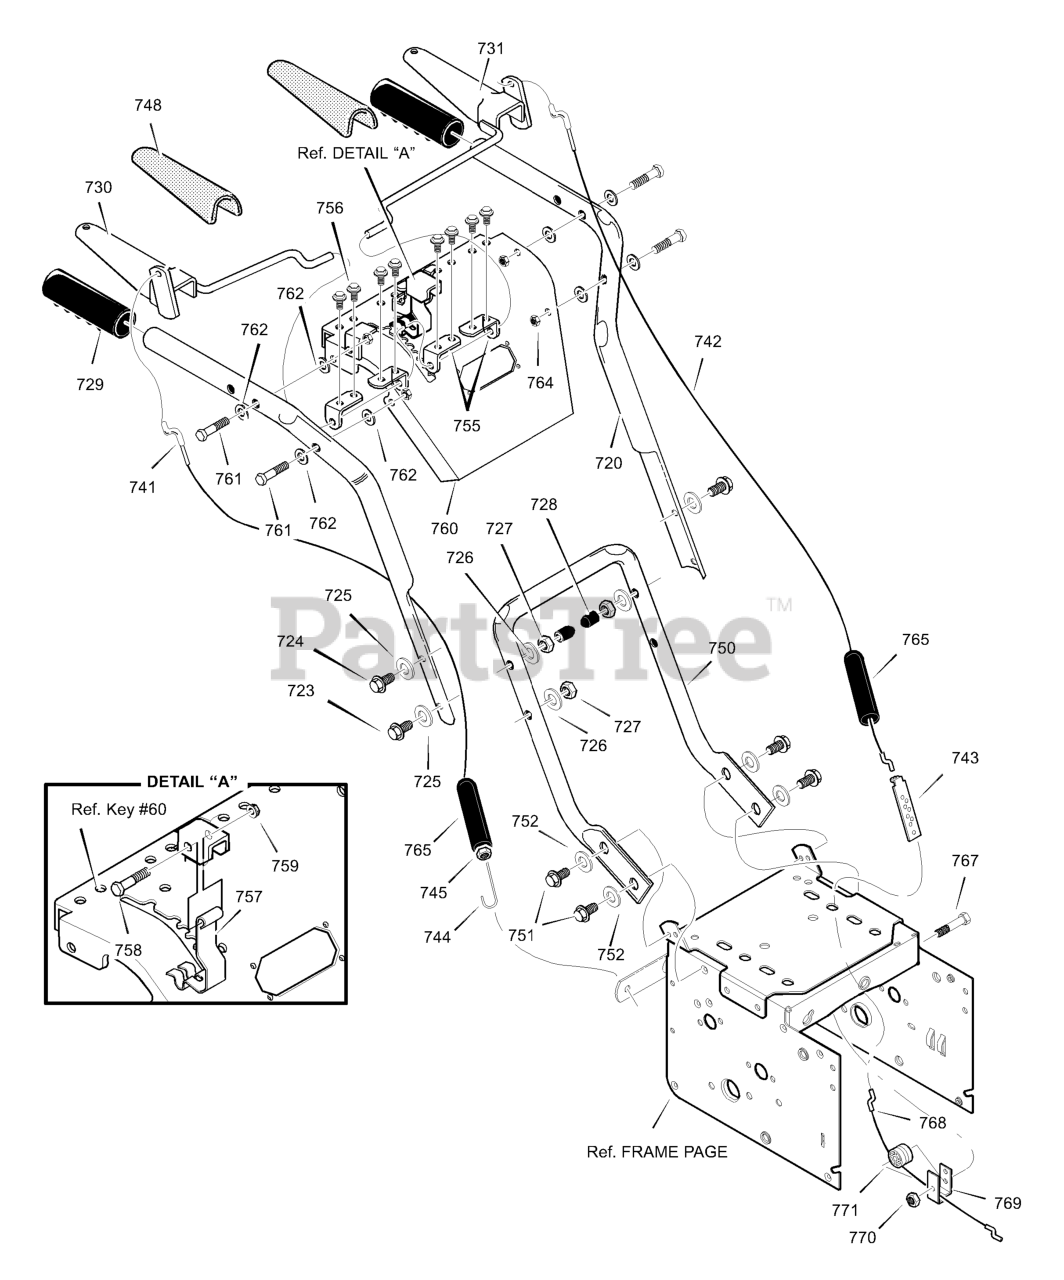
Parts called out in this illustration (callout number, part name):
720	HANDLE, UPPER LH
721	HANDLE, UPPER RH
723	SCREW
724	SCREW
725	WASHER, FLAT
726	WASHER, SPTLK
727	NUT, REGHEX
728	STOP, PLASTIC
729	GRIP-HANDLE
730	LEVER, ASSY CLUTCH DRIVE RH
731	LEVER, ASSY CLUTCH DRIVE LH
741	CABLE, AUGER CLUTCH
742	CABLE, AUGER DRIVE
743	BRACKET, CABLE ADJUSTER
744	SPRING, AUGER CLUTCH
745	NUT, 1/4-20
748	GRIP, CLUTCH HANDLE
750	HANDLE, LOWER
751	SCREW, TAP 5/16-18 X .75
752	WASHER, SPTLK
754	SCREW
755	BRKT, ROD
756	SCREW
757	SPRING, CAM LOCK
758	BOLT, HEX
759	NUT
761	SCREW
762	WASHER, FLAT
764	NUT, HEXFLNG
765	BOOT, CLUTCH SPRING
767	BOLT, HEX 1/4-20 X 1.75 YZ
768	CABLE, LOWER DRIVE 12"
769	BRACKET, CABLE SPOOL YZ
770	NUT
771	SPOOL-CABLE, AUGRT CLUTCH
772	SPRING, AUGER CLUTCH
